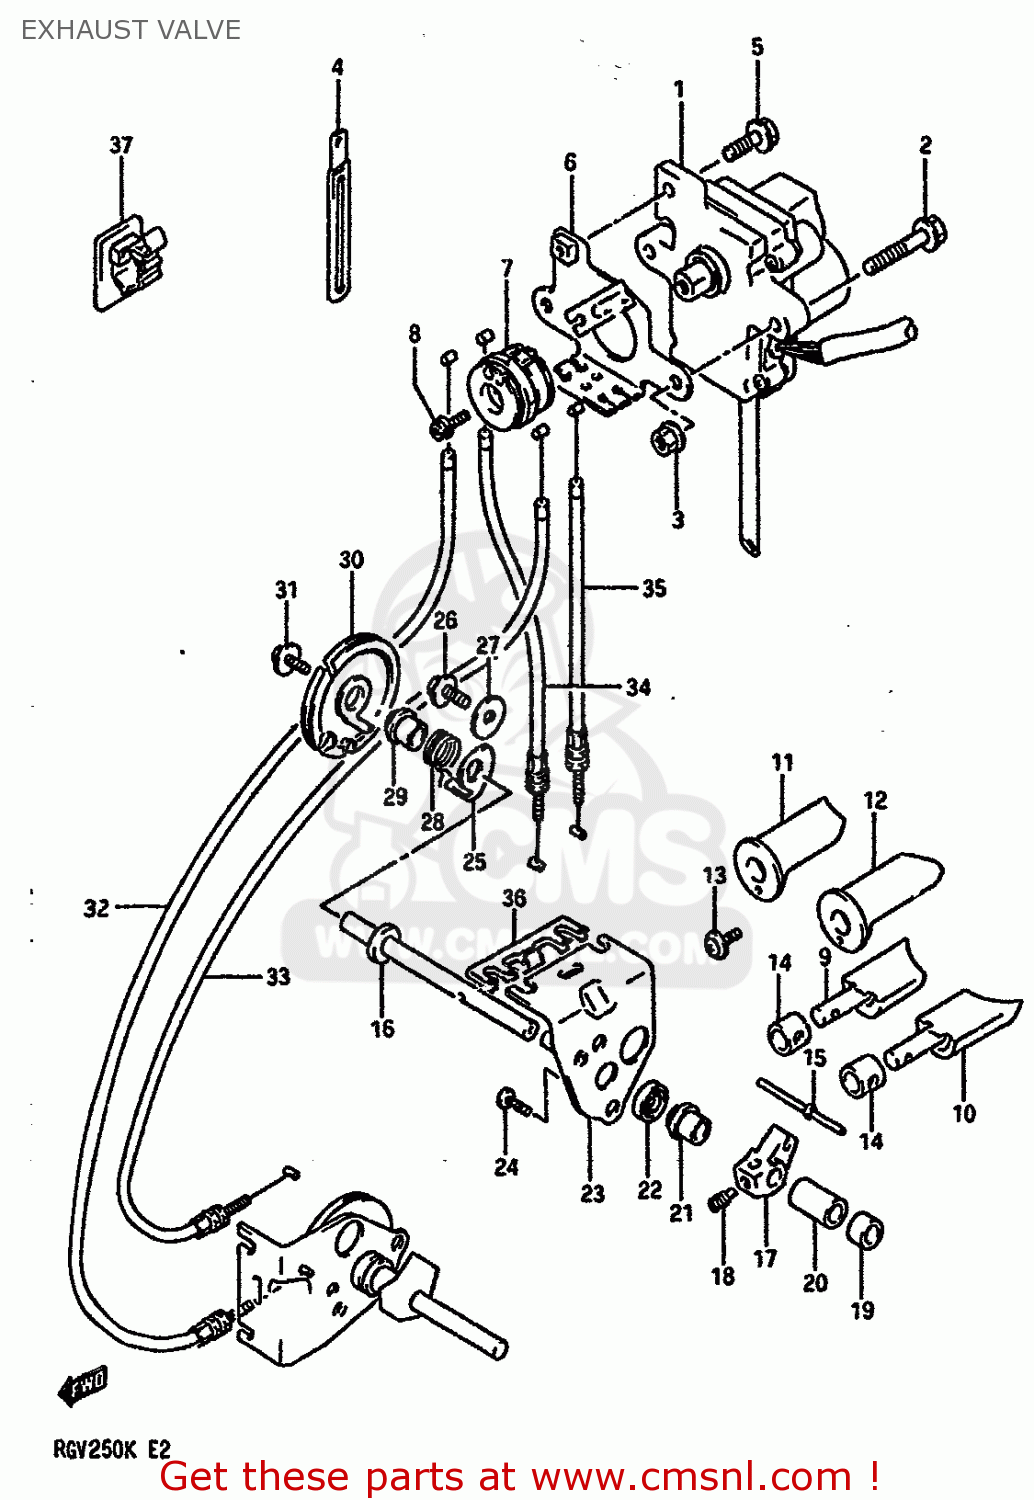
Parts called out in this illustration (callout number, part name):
1	ACTUATOR ASSY,EXHAUST VALVE
2	BOLT
3	NUT
4	CLAMP
5	BOLT
6	BRACKET,CABLE
7	PULLEY,CONTROLLER
8	BOLT
9	VALVE,EXHAUST RH
10	VALVE,EXHAUST LH
11	GUIDE,EXHAUST VALVE RH
12	GUIDE,EXHAUST VALVE LH
13	SCREW
14	SPACER,EXHAUST VALVE
15	PIN,EXHAUST VALVE 48.5MM
16	SHAFT,EXHUAST VALVE
17	ARM,EXHAUST VALVE SHAFT
18	SCREW
19	BUSH(8X12X7)
20	SPACER,EXHAUST VALVE SHAFT
21	BUSH,EXHAUST VALVE NO.2
22	SEAL,OIL(8X16X5)
23	RETAINER,OIL SEAL
24	SCREW 6X12
25	LEVER,EXHUAST VALVE
26	SCREW
27	WASHER
28	SPRING,EXHAUST VALVE LEVER
29	SPACER,EXHAUST VALVE PULLEY
30	PULLEY,EXHAUST VALVE
31	BOLT
32	CABLE,EXHAUST VALVE FR,R
33	CABLE,EXHAUST VALVE FR,L
34	CABLE,EXHAUST VALVE RR,R
35	CABLE,EX VALVE REAR LH
36	STOPPER,CABLE
37	CLAMP
